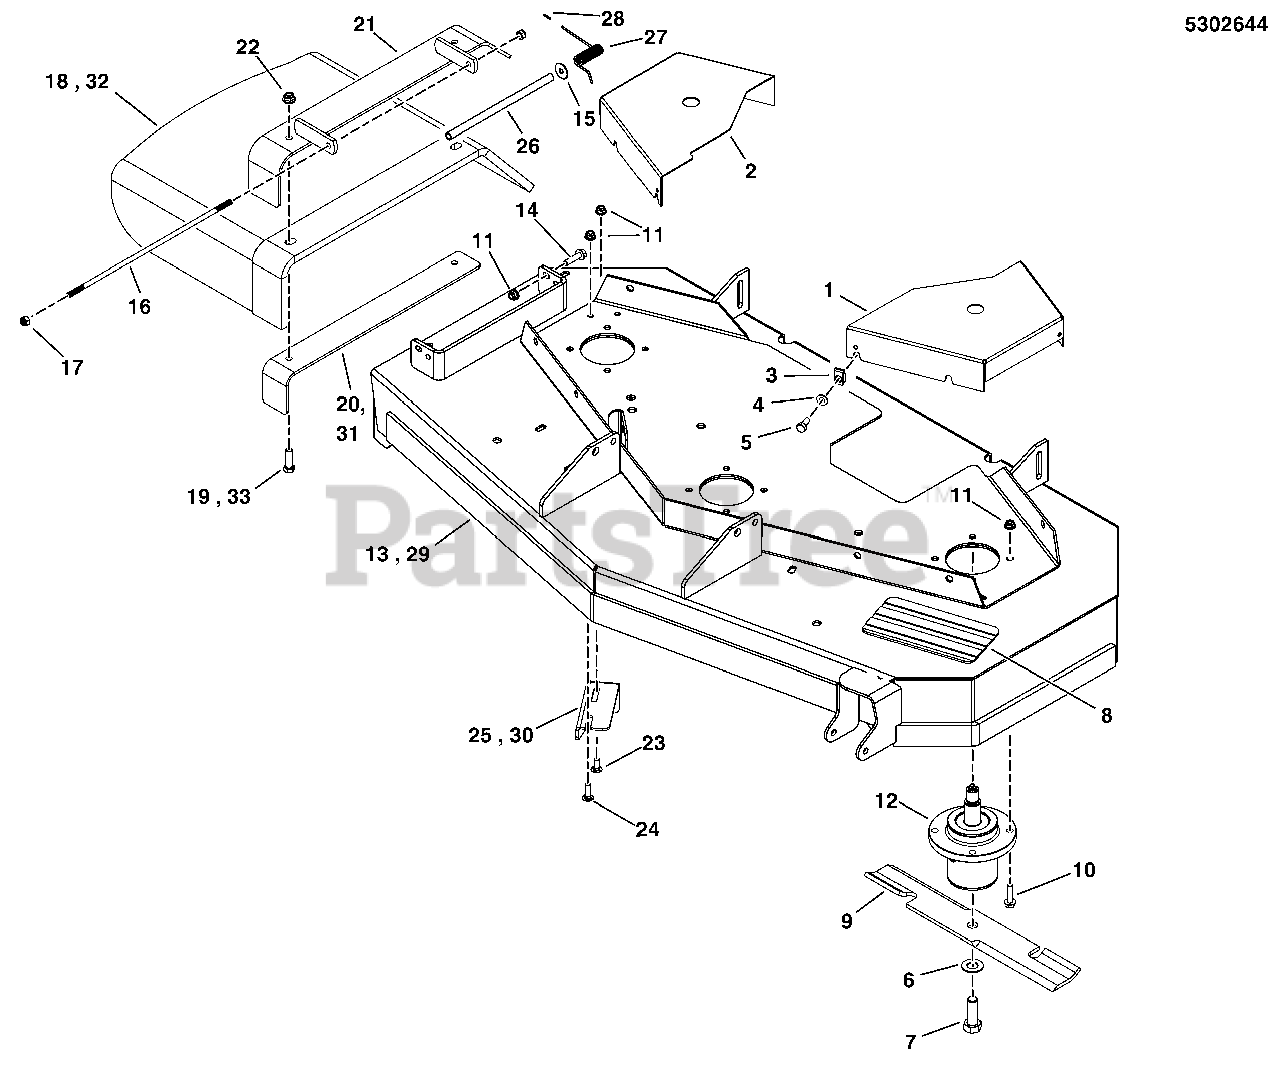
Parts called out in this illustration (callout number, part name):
1	GUARD, 48" MOWER DECK, LH
2	GUARD, 48" MOWER DECK, RH
3	BODY CLIP 5/16-18 X 1/2" DEEP
4	WASHER, 5/16 SAE
5	BOLT, 5/16-18 X 3/4 GD5
6	WASHER, 5/8 GRADE 8, YZ
7	BOLT, 5/8-11 X 1-3/4 GR8
8	SAFETY WALK, 4.00 X 7.50
9	BLADE SET, 48" DECK
10	BOLT, 5/16-18 X 1-1/4" FLANGE
11	NUT, 5/16-18 HEX NYLOCK FLANGE
12	ASSM, SPINDLE, LOW PROFILE
13	DECK SHELL W/ DECALS 48" DECK, 2900 (5407965D)
14	SCREW, 5/16-18
15	WASHER, 5/16 FENDER
16	ROD, BRAKE LINKAGE
17	NUT 5/16-24 HEX NYLON LOCK
18	CHUTE, RUBBER, BENT
19	BOLT, 3/8-16 X 1-1/4 GD5 YZ
20	SUPPORT, DISCHARGE CHUTE, 48/52 - BLK
21	WELD, FRAME CHUTE, 44/48/52 - BLK
22	NUT, 3/8-16 HEX NYLOCK FLANGE
23	BOLT, 5/16"-18 CARRIAGE, 3/4"
24	BOLT, 5/16"-18 CARRIAGE, 1"
25	PLATE, DEFLECTOR - BLK
26	TUBE, 1/2 X 3/8 X 8.00LG BLACK POLY
27	SPRING, TORSION
28	CAP, PROTECTOR, .120 ID
29	DECK SHELL W/ DECALS, 48" DECK, 2900 (5409884D)
30	PLATE, DEFLECTOR - BLK
31	SUPPORT, DISCHARGE CHUTE - BLK
32	CHUTE, RUBBER DISCHARGE (5104441)
33	BOLT, 3/8-16 X 1-1/2, CARRIAGE, GD5, CZ
